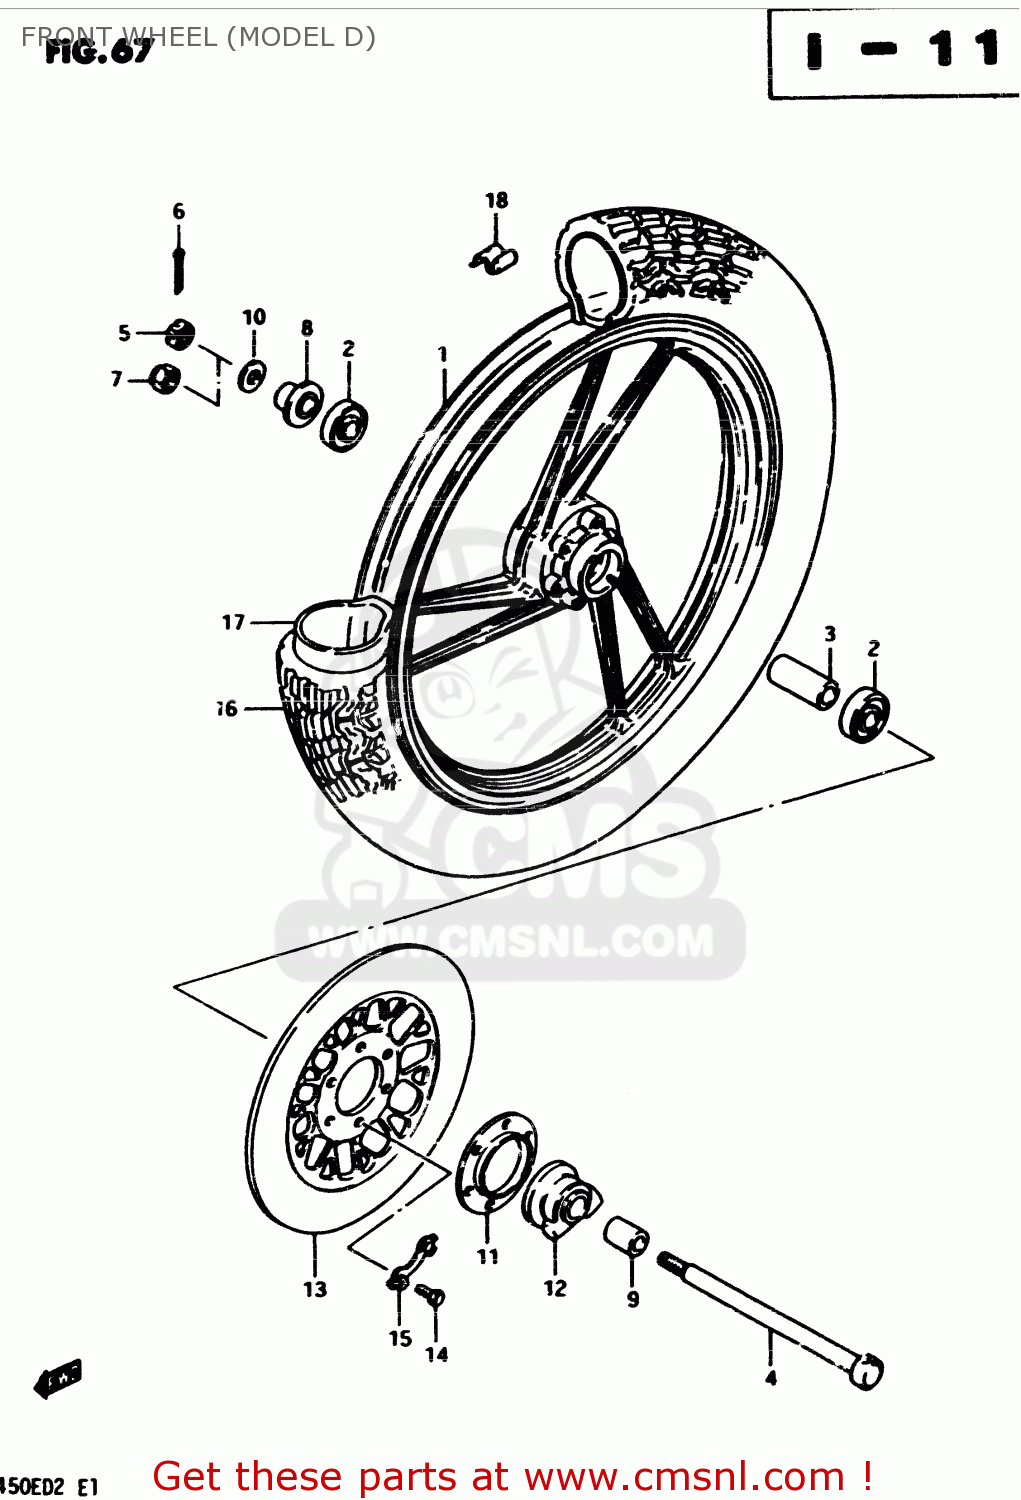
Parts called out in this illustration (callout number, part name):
1	WHEEL (1.60X18)
2	BEARING
3	SPACER(15.3X21.7X63)
4	AXLE,FRONT
5	NUT 12MM
6	COTTER PIN
7	NUT
8	SPACER,FR HUB BEARING,R
9	SPACER(15X22X30)
10	WASHER
11	DUST SEAL,SPEEDOMETER GEAR BOX
12	BOX ASSY,SPEEDOMETER GEAR
13	DISC,FR BRAKE
14	BOLT(8X25)
15	WASHER
16	TIRE,FRONT
17	TUBE,INNER
18	BALANCER,WHEEL
